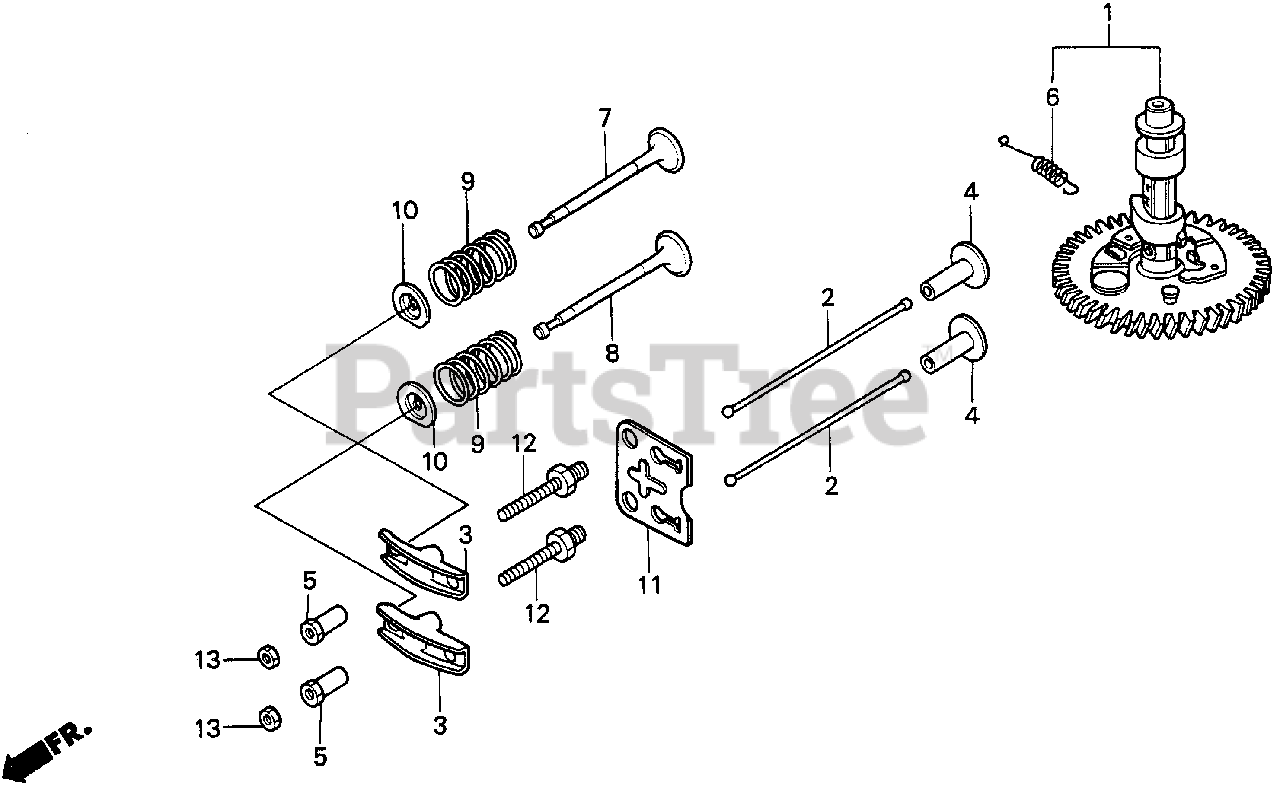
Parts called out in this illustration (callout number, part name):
1	CAMSHAFT ASSY.
2	ROD, PUSH
3	ARM, VALVE ROCKER
4	LIFTER, VALVE
5	PIVOT, ROCKER ARM
6	SPRING, WEIGHT RETURN
7	VALVE, IN.
8	VALVE, EX.
9	SPRING, VALVE
10	RETAINER, IN. VALVE SPRING
10	RETAINER, VALVE SPRING (EXHAUST SIDE)
11	PLATE, PUSH ROD GUIDE
12	BOLT, PIVOT (8MM)
13	NUT, PIVOT ADJ.
